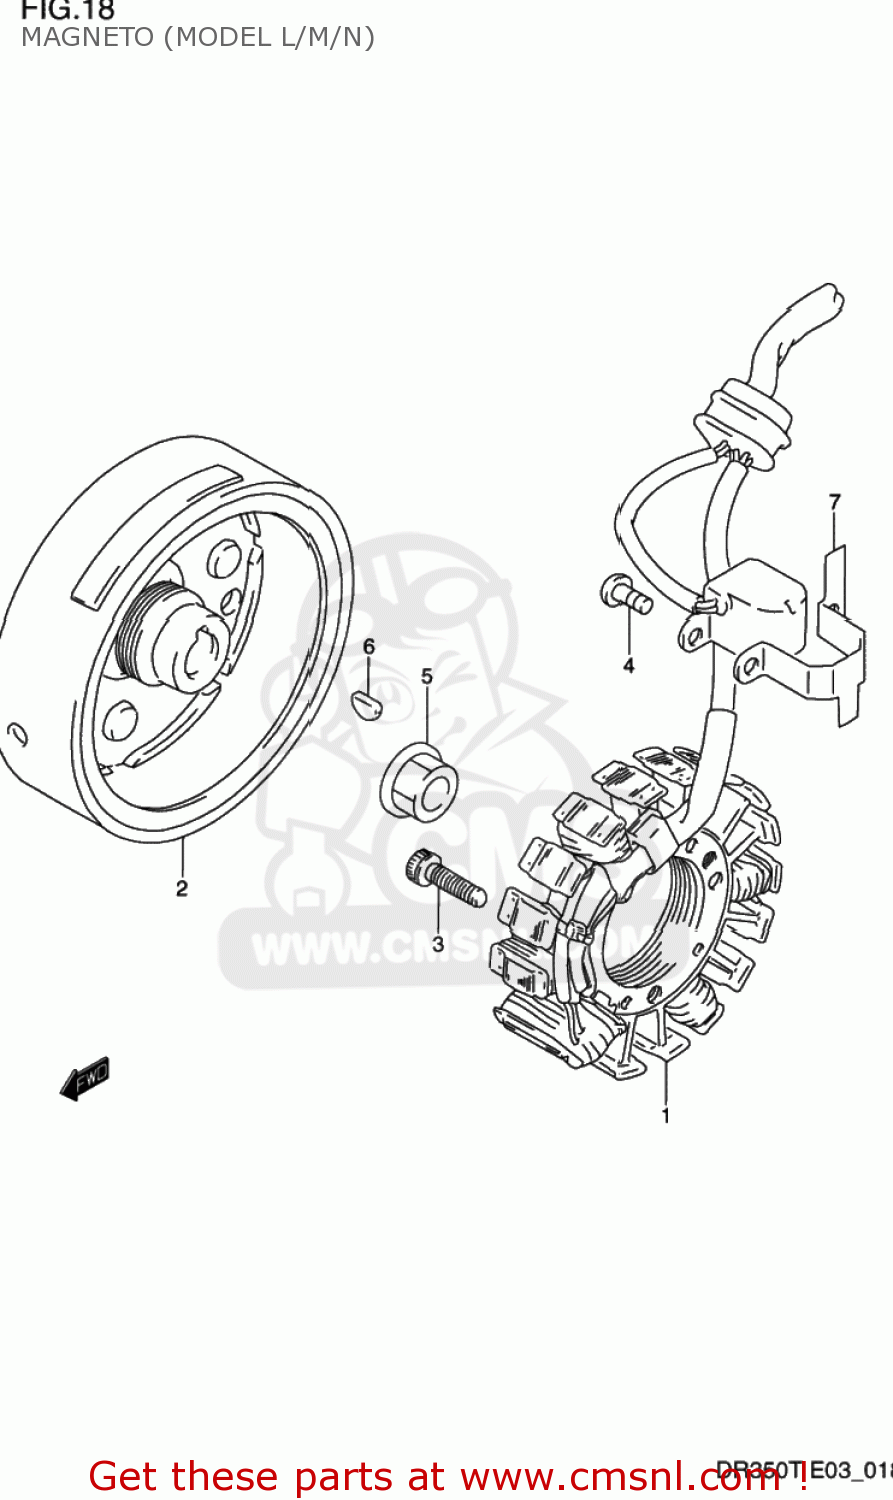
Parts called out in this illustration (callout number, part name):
1	STARTER ASSY
2	ROTOR
3	BOLT
4	SCREW
5	NUT
6	KEY 4MM
7	CLAMP,MAGNETO LEAD WIRE
